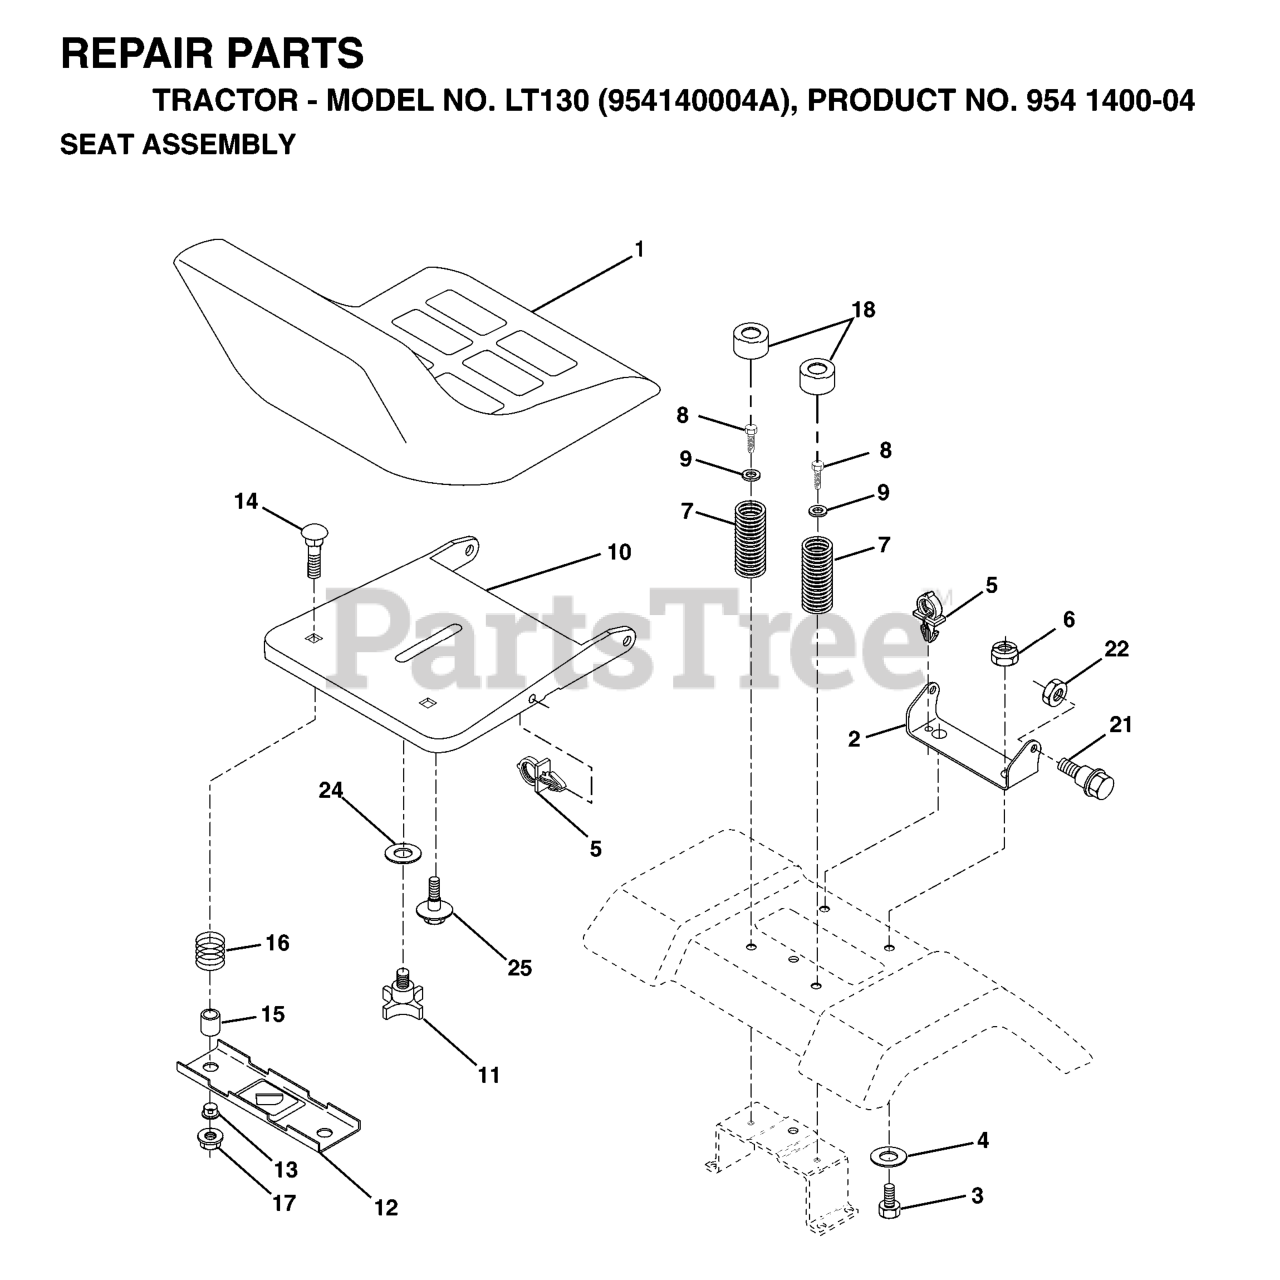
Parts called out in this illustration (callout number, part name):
1	SEAT
2	SEAT PIVOT BRKT
3	BOLT
6	NUT
7	SPRING COMPRESSION
8	SCREW GTV
9	WASHER
10	PAN, SEAT
11	KNOB 1/2" YT
12	BRKT SWITCH
14	Bolt Rdhd. Sht. Nk 1/4-20 x 1-3/8
15	SPACER SPLIT 28X.96
17	NUT T
18	CAP SPRING
21	BOLT SHOULDER 5/16-18
22	NUT.71038.31-18.HEX.NYLOCK
25	BOLT,SHOULD
